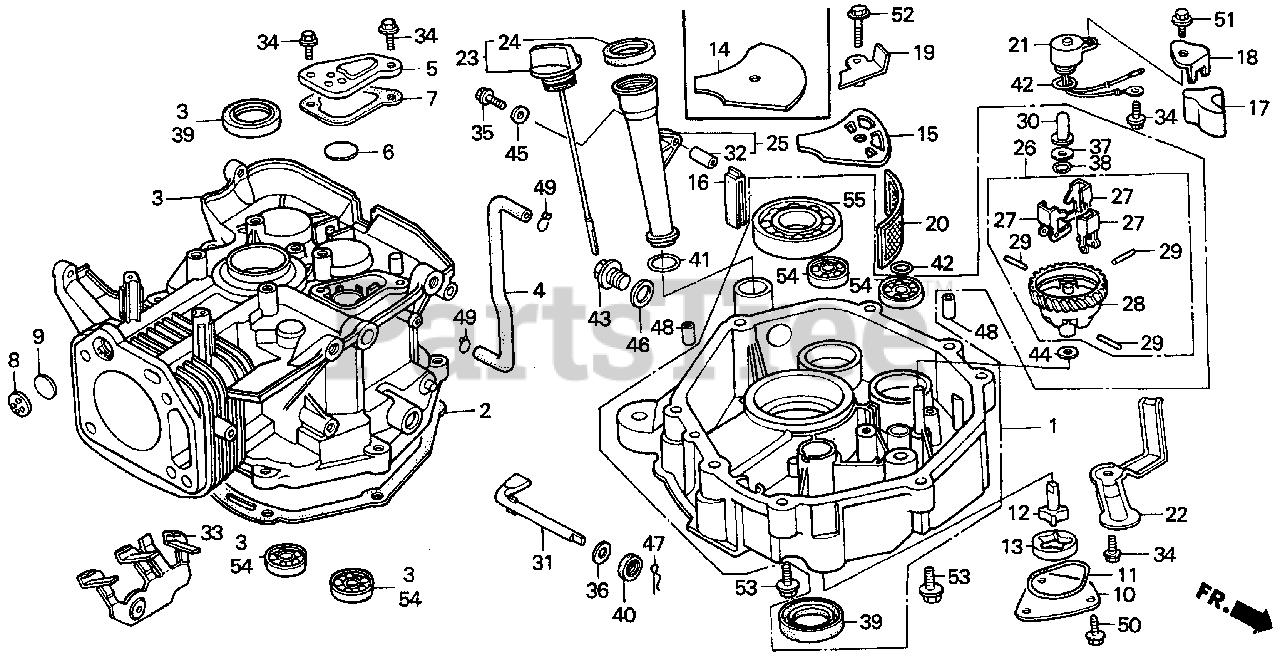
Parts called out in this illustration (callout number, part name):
1	PAN ASSY., OIL
2	GASKET, OIL PAN
3	CYLINDER ASSY.
4	TUBE, BREATHER
5	CAP, BREATHER CHAMBER
6	VALVE, BREATHER
7	GASKET, BREATHER CAP
10	COVER, OIL PUMP
11	O-RING, PUMP COVER
12	ROTOR (INNER)
13	ROTOR, OIL PUMP (OUTER)
15	PLATE, OIL FILTER
16	RUBBER, OIL RETURN
17	STOPPER, OIL
18	PLATE, OIL STOPPER
19	PLATE, SUCTION
20	SCREEN, OIL FILTER
21	SWITCH, OIL LEVEL
22	PROTECTOR, SWITCH
23	CAP ASSY., OIL FILLER
24	GASKET, OIL FILLER CAP
25	EXTENSION, OIL FILLER
26	GOVERNOR ASSY.
27	WEIGHT, GOVERNOR
28	HOLDER, GOVERNOR WEIGHT
29	PIN, GOVERNOR WEIGHT
30	SLIDER, GOVERNOR
31	SHAFT, GOVERNOR ARM
32	COLLAR, EXTENSION
33	STAY, SWITCH WIRE CLAMP
34	BOLT, FLANGE (6X12) (CT200)
35	BOLT, FLANGE (6X35)
36	WASHER, THRUST (8.1MM)
37	WASHER (6X16)
38	CLIP, GOVERNOR HOLDER
39	OIL SEAL (35X52X8)
40	OIL SEAL (8X14X5)
41	O-RING (22.5X2.2)
42	O-RING (11.8X2.4)
43	BOLT, DRAIN PLUG (20MM)
44	WASHER, PLAIN (6MM)
45	WASHER, PLAIN (6MM)
46	WASHER, DRAIN PLUG (20MM)
47	PIN, LOCK (8MM)
48	PIN A, DOWEL (8X14)
49	CLIP, TUBE (C11)
50	BOLT, FLANGE (6X12)
51	BOLT, FLANGE (6X12)
51	BOLT, FLANGE (6X16)
52	BOLT, FLANGE (6X25)
53	BOLT, FLANGE (8X40)
54	BEARING, RADIAL BALL (6202)
55	BEARING, RADIAL BALL (6207)
NI	GOVERNOR KIT
